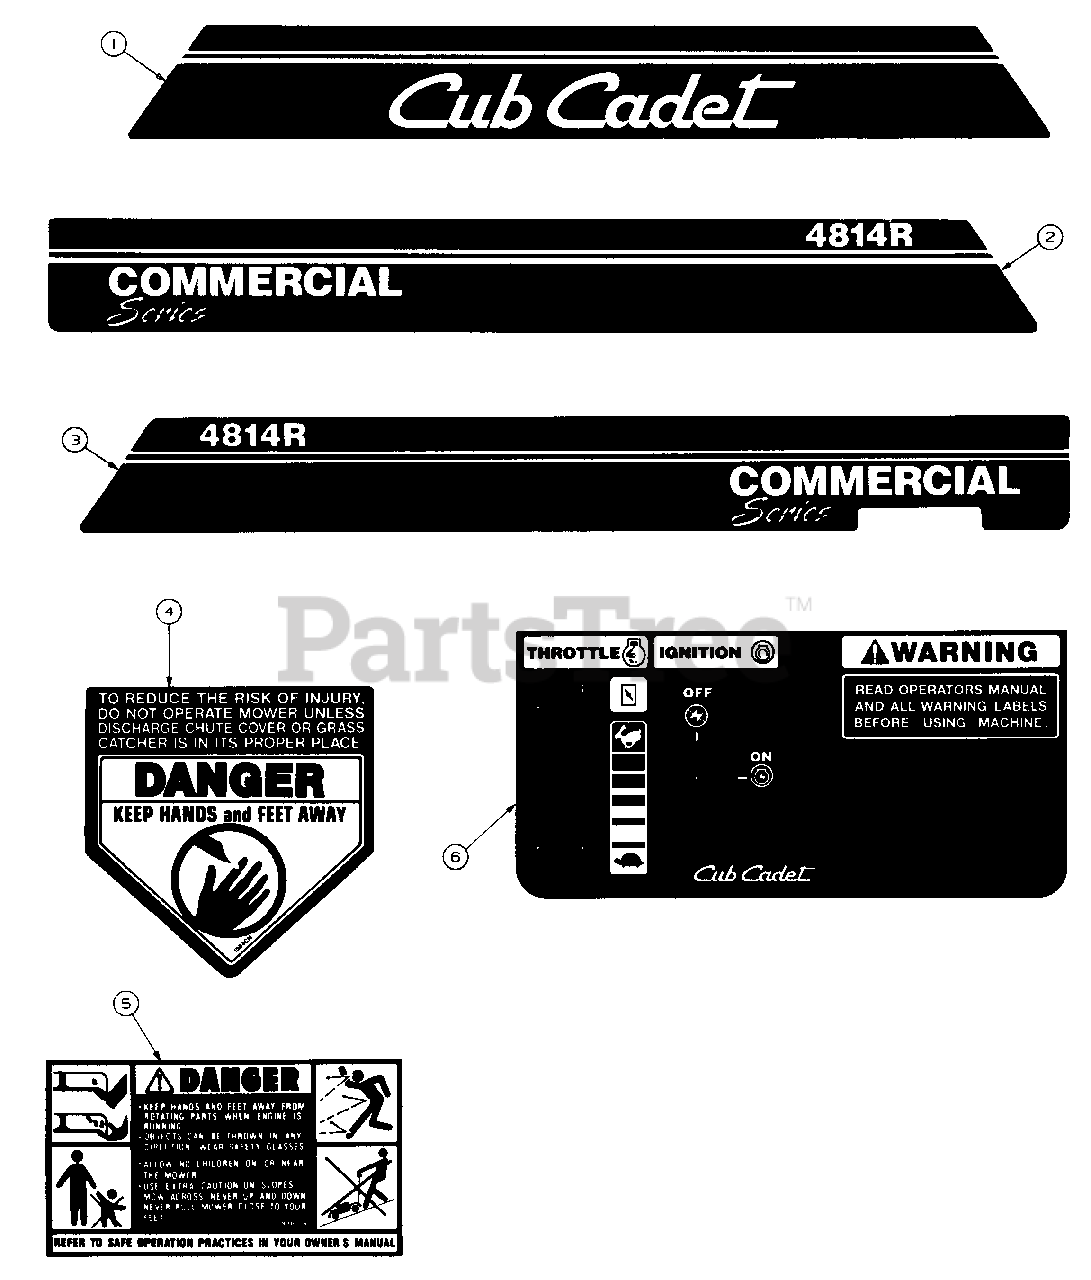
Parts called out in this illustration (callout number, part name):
1	Graphic, Belt Cover Front
2	Graphic 4814R, Belt Cover Right
3	Graphic 4814R, Belt Cover Left
4	Graphic, Danger Cut Finger
5	Graphic, Danger
6	Graphic, Control Panel
